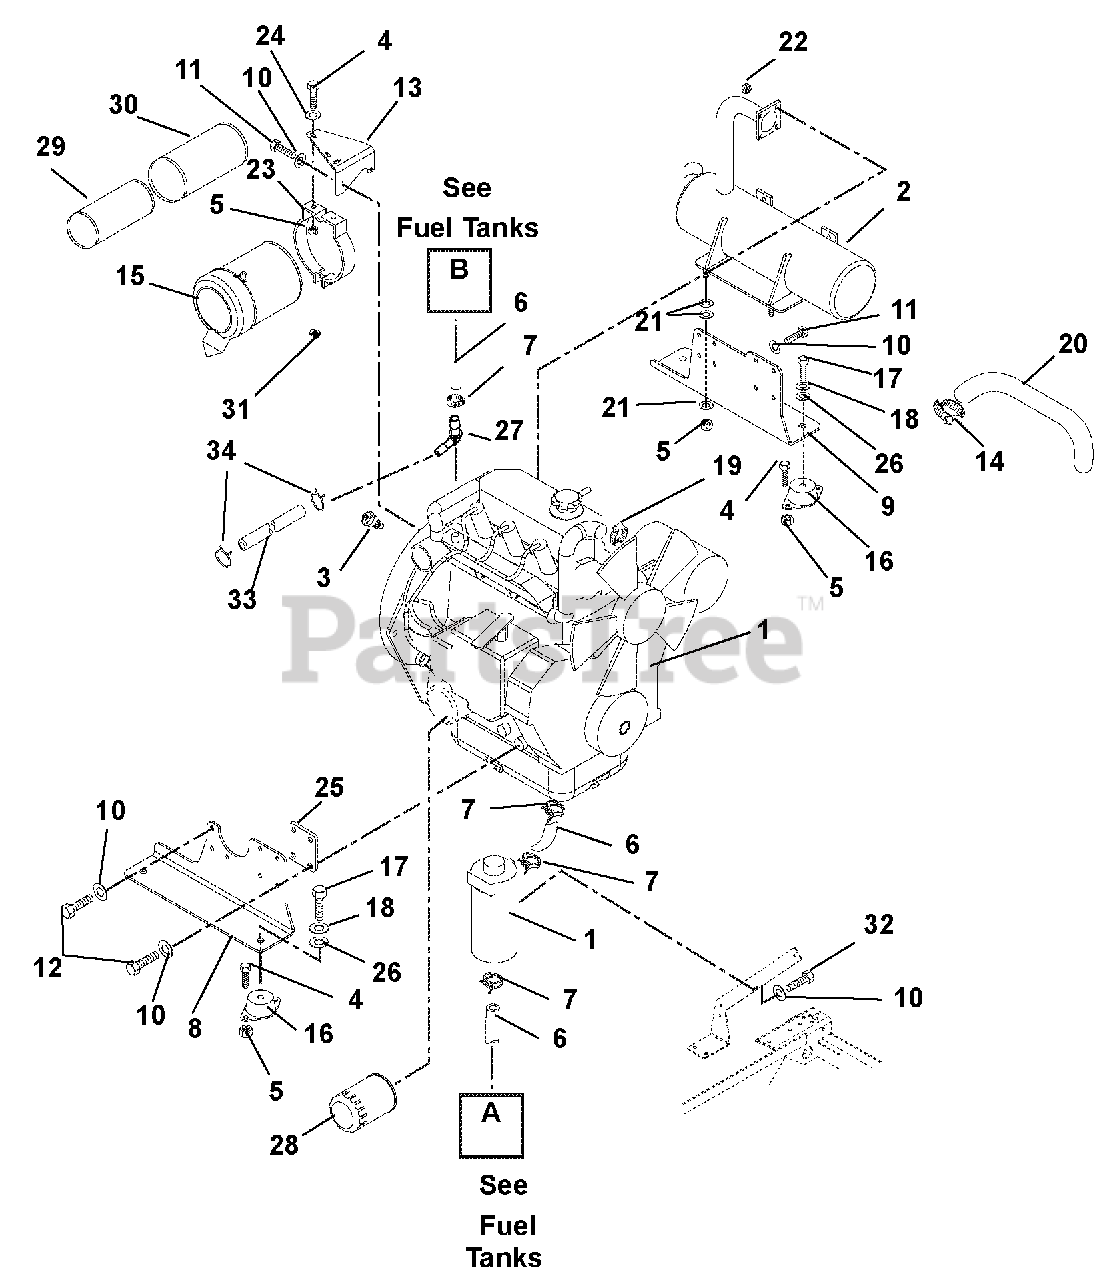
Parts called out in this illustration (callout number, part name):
1	Engine, 27HP Daihatsu Diesel (950D) (582447-0405-E2) (992316, 322, 324)
2	Muffler (992316, 322, 324)
3	Sender, Temperature
4	Bolt, Hex .31-18 x .75 Grade 5
5	Nut, Locking Top Flange .31-18
6	Gas Line, Bulk .31" ID
7	Hose, Clamp
8	Mount, Engine Right Hand
9	Mount, Engine Left Hand
10	Washer, Lock .31 x .078 Regular
11	Bolt, Hex M8-1.25 x 20
12	Bolt, Hex M8 x 1.25 x 25 Grade 8
13	Bracket, Air Cleaner
14	Clamp, #32 (1.56" – 2.50") Dia. Hose
15	Assembly, Air Cleaner
16	Mount, Engine
17	Bolt, Hex .50-20 x 1.00 Grade 5
18	Washer, Locking .50 x .125 Regular
19	Clamp, Hose 1.50 x .81 x 1.42
20	Hose, Air Cleaner (992316, 322, 324)
21	Washer, Flat Steel .38 x .875 x .083
22	Nut, Locking Top M8-1.25
23	Bracket, Air Cleaner Mount
24	Washer, Flat Steel .38 x .875 x .083
25	Spacer, Engine Mounting
26	Washer, Flat Steel .531 x 1.06 x .095
27	Reducer, Hose, Elbow .31ID/.25ID
28	Oil Filter
29	Element, Inner Safety
30	Element, Outer Primary
31	Plug, Pipe .125-27
32	Bolt, Hex M6-1 x 16
33	Hose, .25 Low, Perm Bulk Gas
34	Clamp, Fuel Line
